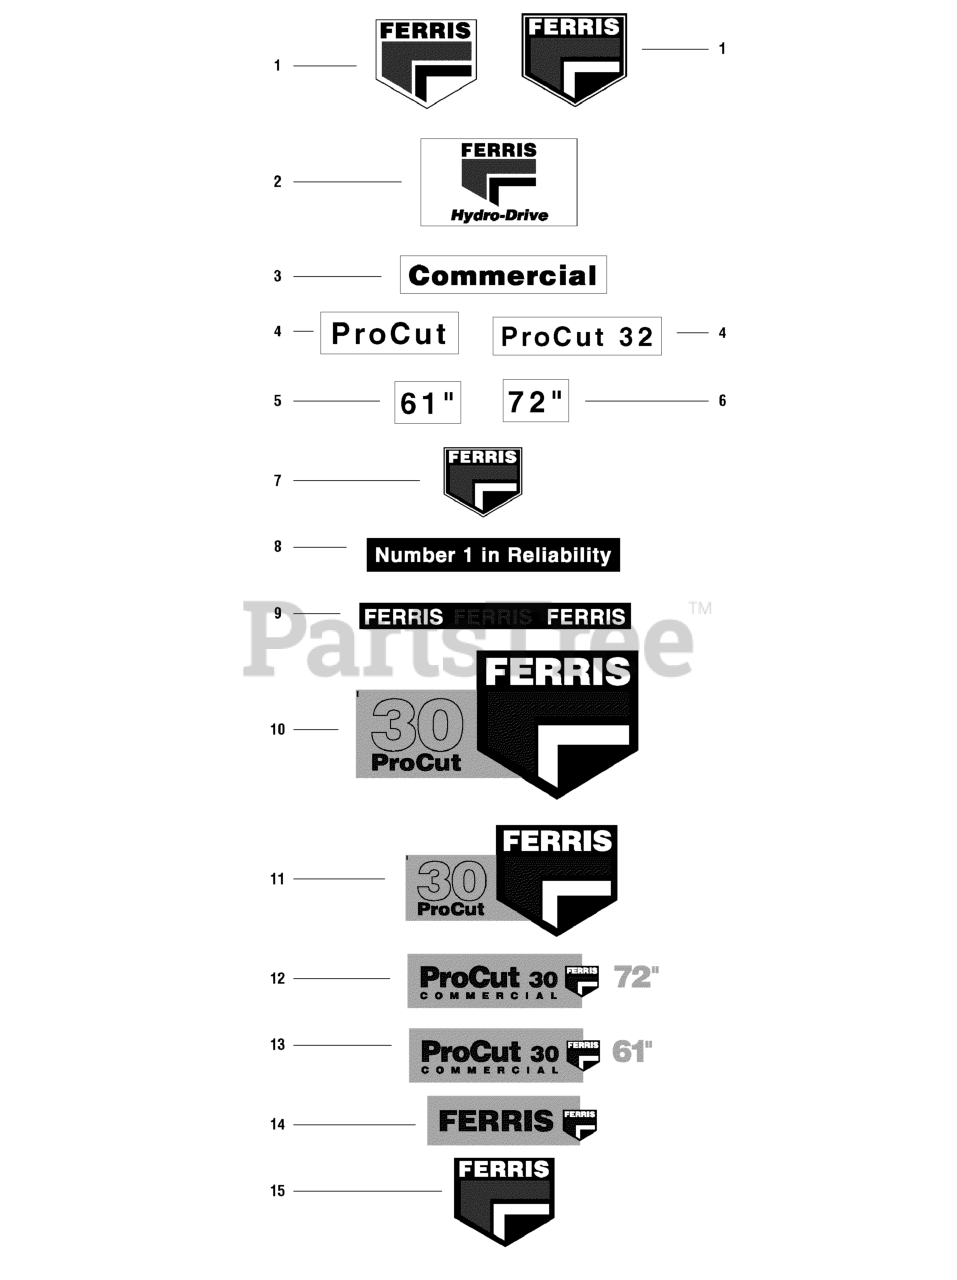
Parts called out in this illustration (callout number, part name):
1	DECAL, Ferris Logo, 10-3/4"
2	DECAL, Hydro Drive
3	DECAL, Commercial
4	DECAL, ProCut
4	DECAL, ProCut 32
5	DECAL, 61"
6	DECAL, 72"
7	DECAL, Ferris Logo, 6-3/8"
8	DECAL, Number One In Reliability
9	DECAL, Ferris Text
10	DECAL, Ferris Logo (72" deck)
11	DECAL, Ferris Logo (61" deck)
12	DECAL, ProCut 3072
13	DECAL ProCut 3061
14	DECAL, FERRIS TEXT & LOGO
15	DECAL, Ferris Logo, 6-3/8"
